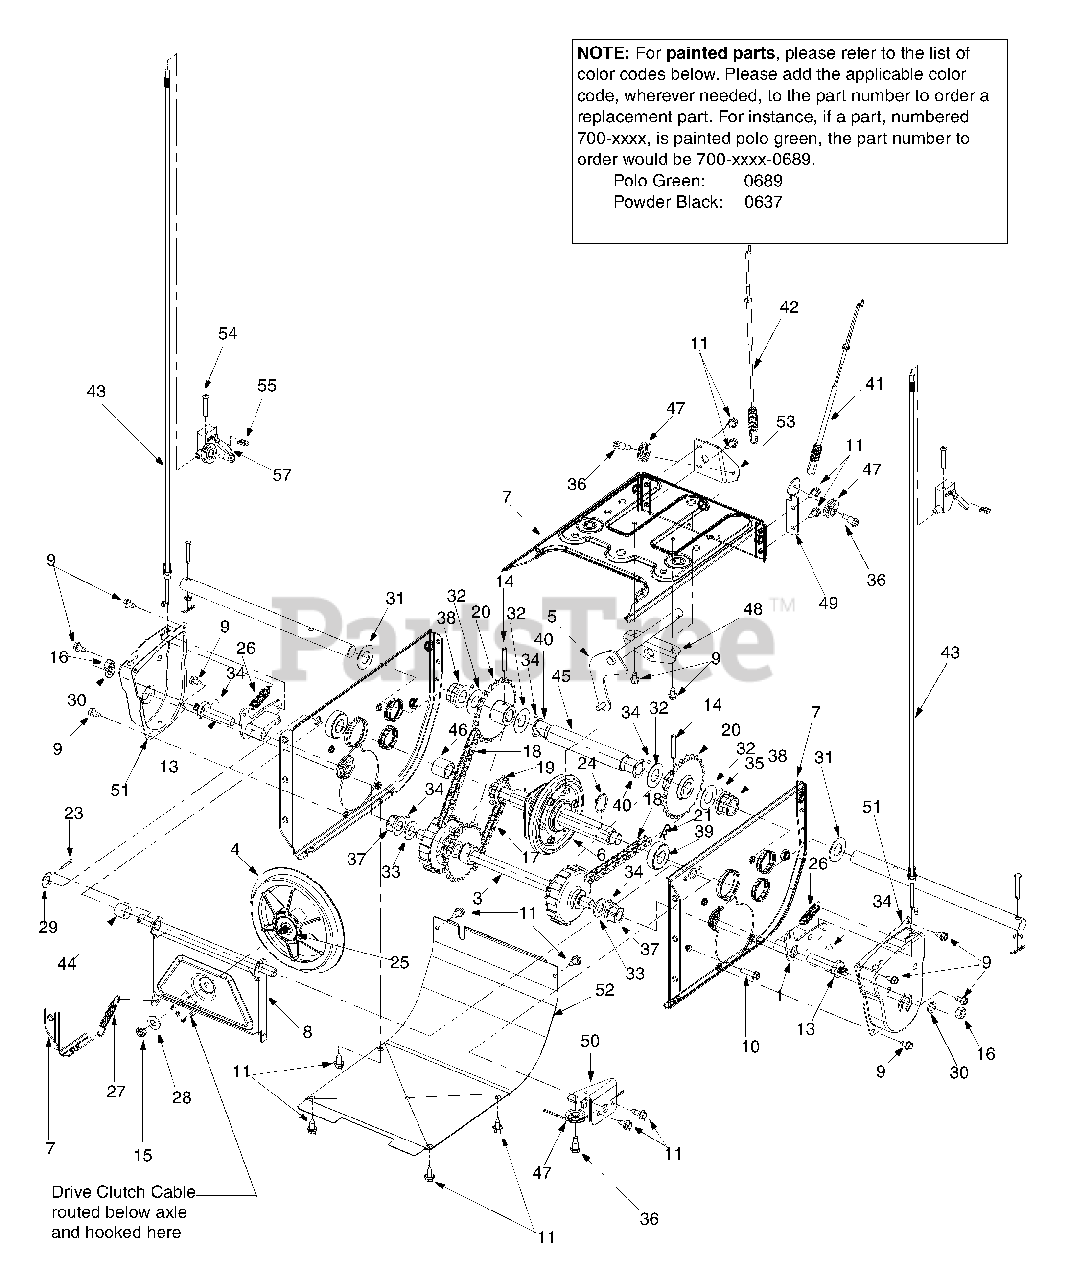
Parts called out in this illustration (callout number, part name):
3	Shift Assembly: Steerable Drive
4	Friction Wheel Disc Assy.
6	Bearing
10	Hex Washer Hd. TT Screw 1/4-20 x 1.25"
11	Hex Washer Hd. TT Screw 1/4-20 x .625"
13	Actuator Shaft
15	Jam Nut 3/8-24 Gr.8
16	Hex Nut: 3/8-16
17	Chain
18	Chain
19	Sprocket: 10T
20	Sprocket
21	Cotter Pin
23	Cotter Pin
24	Snap Ring
25	Adhesive: Loctite
26	Extension Spring
27	Extension Spring
28	Bell Washer
29	Flat Washer
30	Lock Washer
32	Flat Washer
33	Flat Washer
34	Lubricant: 6 in !
35	Grease
36	Shoulder Screw
37	Hex Flange Bearing
38	Hex Flange Bearing
39	Ball Bearing
40	Flange Bushing
41	Auger Clutch Cable
42	Drive Clutch Cable
43	Steering Cable
44	Spacer
45	Support Tube: Axle
46	Spacer
47	Roller Cable
55	Weld Nut
57	Turn Trigger
